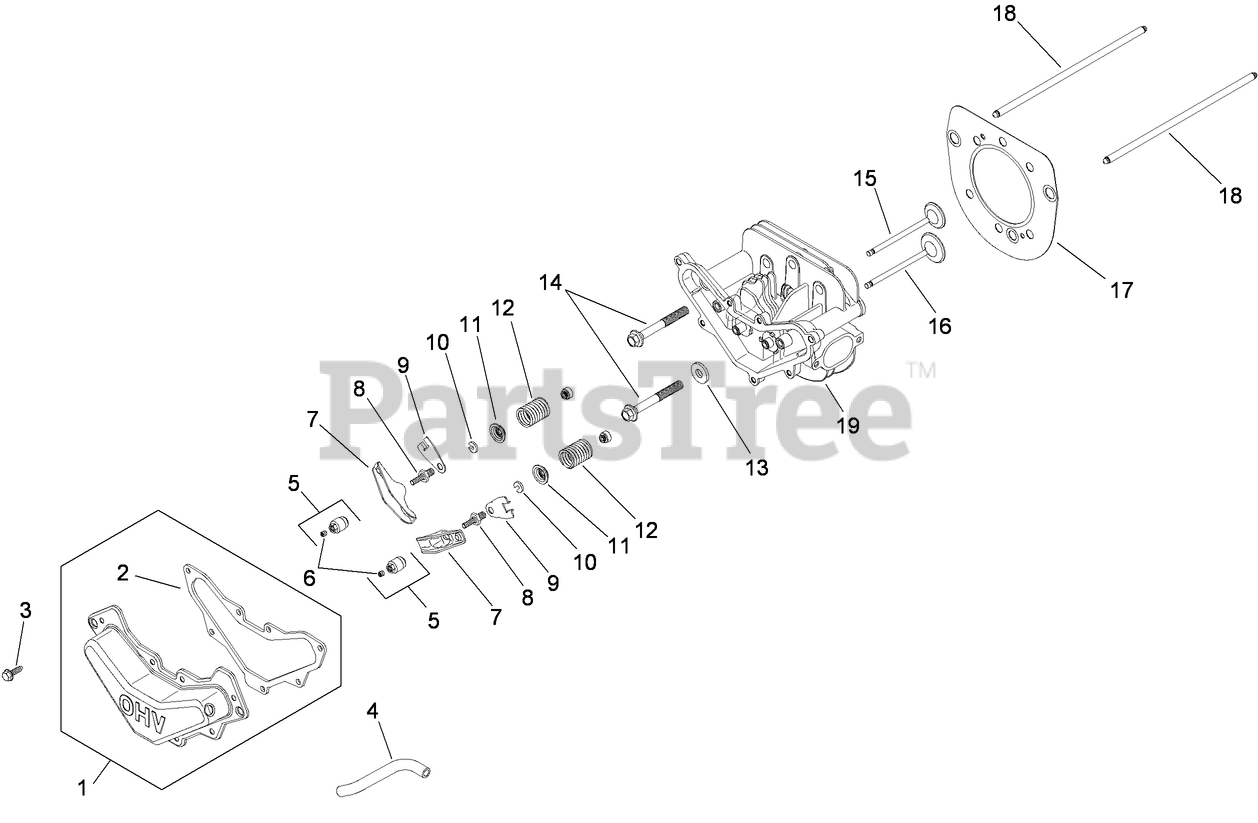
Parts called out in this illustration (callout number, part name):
1	Valve Cover Kit (Includes 2)
2	Gasket-cover, valve
3	SCREW-HHFTF (M6X1.0X20)
4	HOSE-BREATHER
5	ROCKER PIVOT ASM (INCLUDES REF 6)
6	Screw-Set
7	Arm-Rocker
8	STUD-ROCKER
9	Plate-Guide, Push Rod
10	Lock-Retainer
11	Cap-Spring, Valve
12	Spring-Valve
13	Washer-Flat (1/2)
14	Screw-Flange, Hex (M10x1.5x37)
15	Valve-Exhaust
16	Valve-Intake
17	Cylinder Head Gasket Kit (Includes 2, 13-14)
18	Rod-Push
19	CYLINDER HEAD KIT
